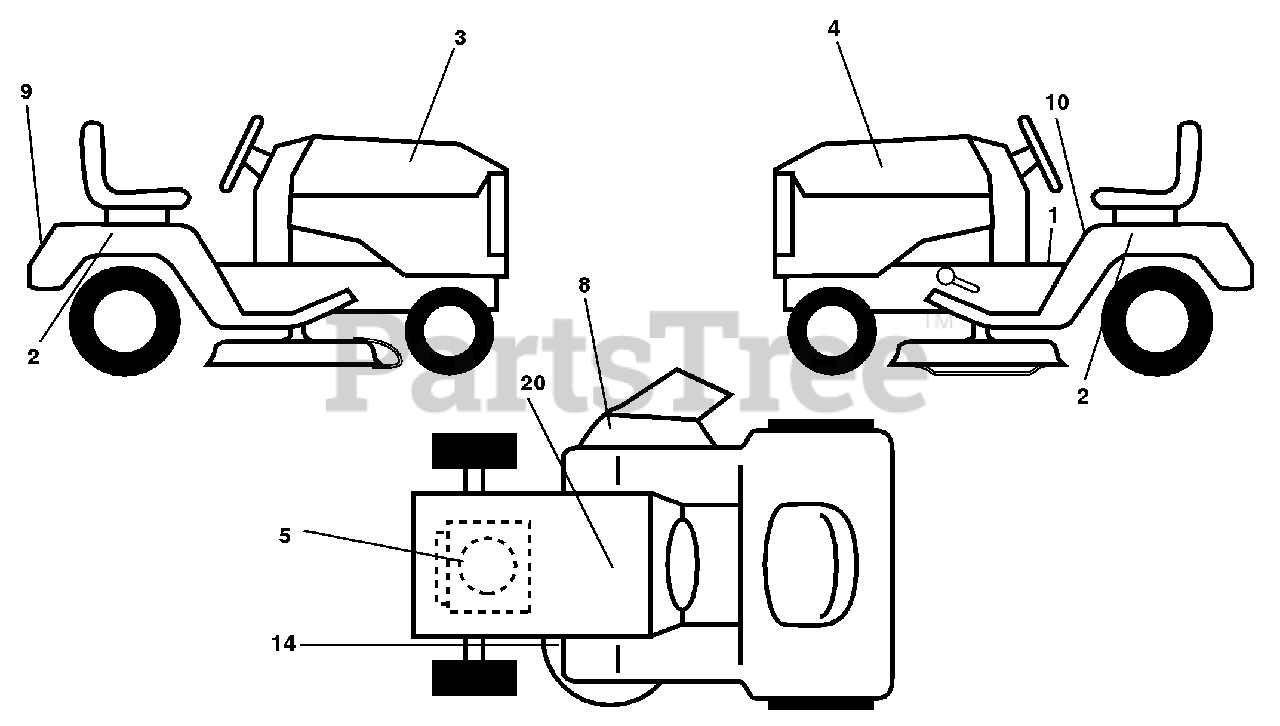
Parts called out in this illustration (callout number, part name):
1	Decal Oper Step Thru E/F
2	Decal Fender Auto Husq. Radius
3	Decal Hood RH
4	Decal Hood LH
5	Decal Engine
8	Decal Warning
9	Decal Fender Husq
10	Decal Fender Danger E/F
14	Decal V-Belt Schematic
20	Decal Bat Dan/Psn
